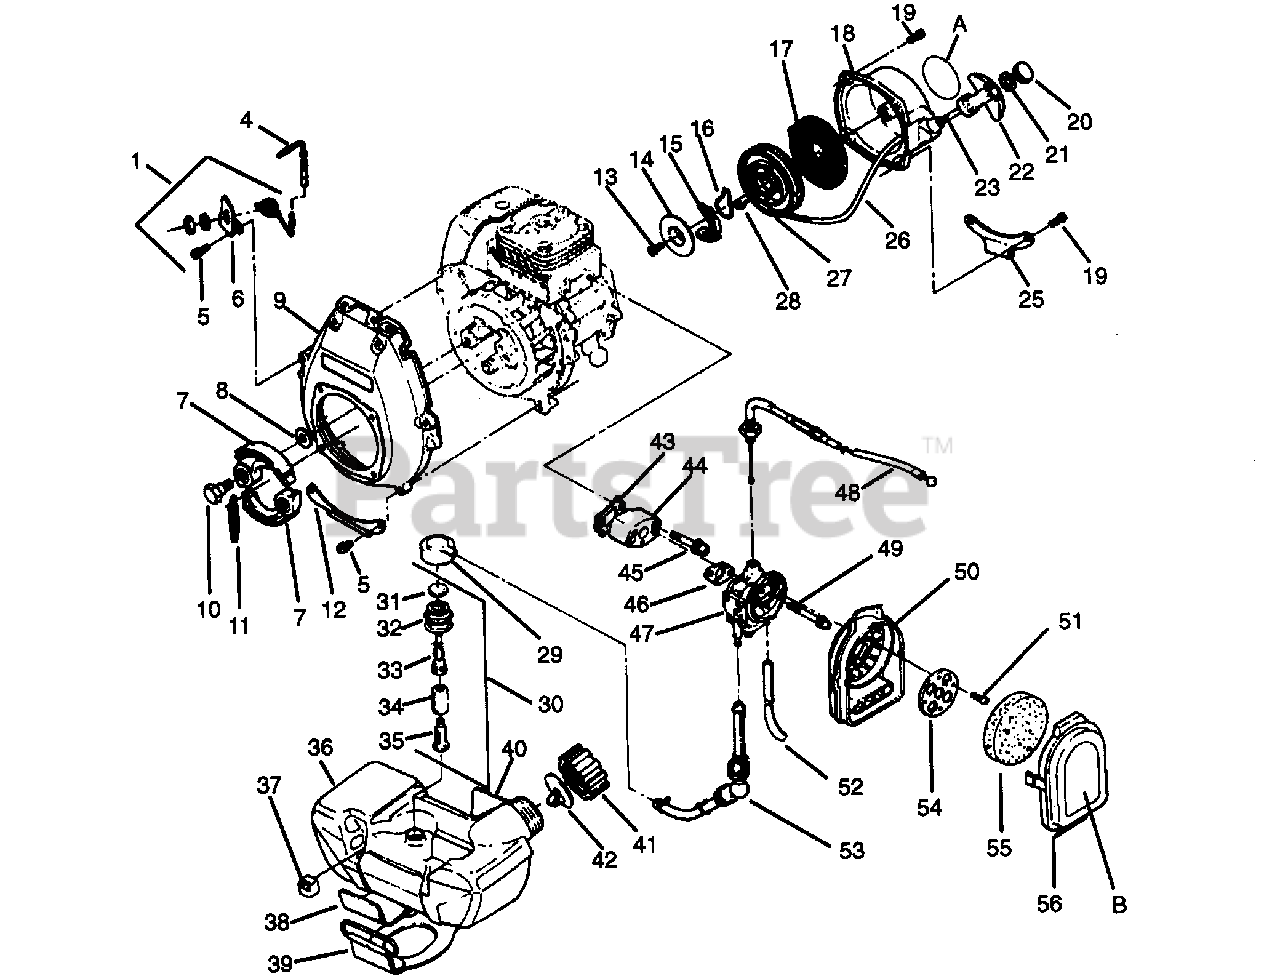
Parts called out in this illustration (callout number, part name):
1	Switch Stop
4	Lead Wire Switch
7	Clutch Shoe
9	Crankcase./Fan Hsg. Ass'y. on Page 3)
10	Clutch Pin
15	Recoil Pawl
16	Recoil Spring
17	Recoil Spring
18	Recoil Starter Ass'y. (Inc.13-17,23,26-28)
26	Rope Kit
27	Recoil Reel
29	Tank Cap Strainer
30	Fuel Strainer Ass'y. (Inc. #31-35)
36	Fuel Tank Ass'y. (Inc. #41 & 42)
37	Fuel Tank Damper
38	Fuel Tank Damper
39	Fuel Tank Band
40	Fuel Tank Damper
41	Tank Cap
42	Breather Cap
44	Insulator
47	Carb. Ass'y.
48	Throttle Cable
50	Air Cleaner Case
55	Air Cleaner
A	XR-200 (Not a serviceable part)
B	YP200 & XR-200-Type 1
B	YP200 & XR-200-Type II; PP200 Type 1
